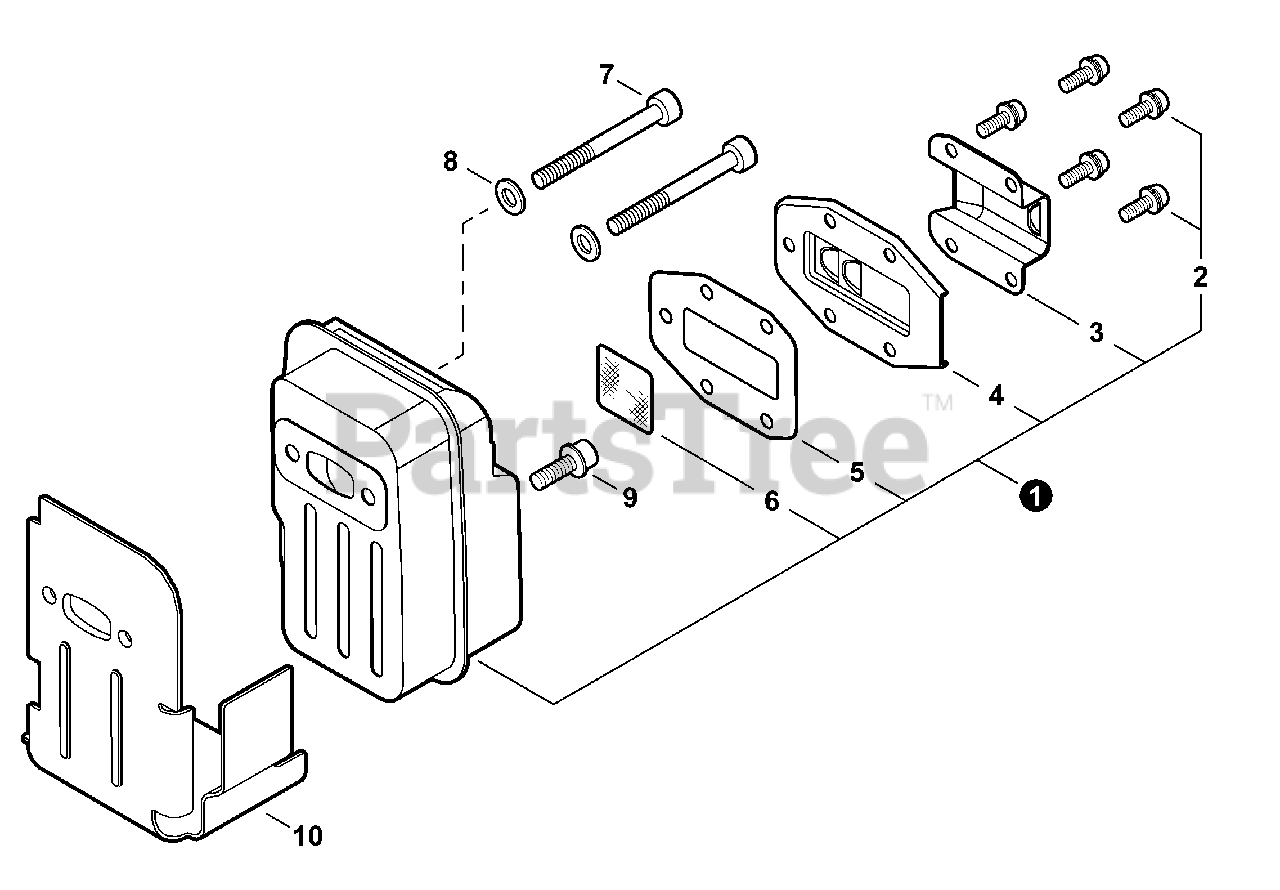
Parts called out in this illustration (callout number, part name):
1	MUFFLER ASSY
2	SCREW M4×8
3	OUTLET, EXHAUST
4	GUIDE, EXHAUST
5	GASKET, EXHAUST
6	SCREEN, SPARK ARRESTER
7	BOLT M5×55
8	WASHER SS 5mm
9	BOLT 5×12
10	HEAT SHIELD, EXHAUST
